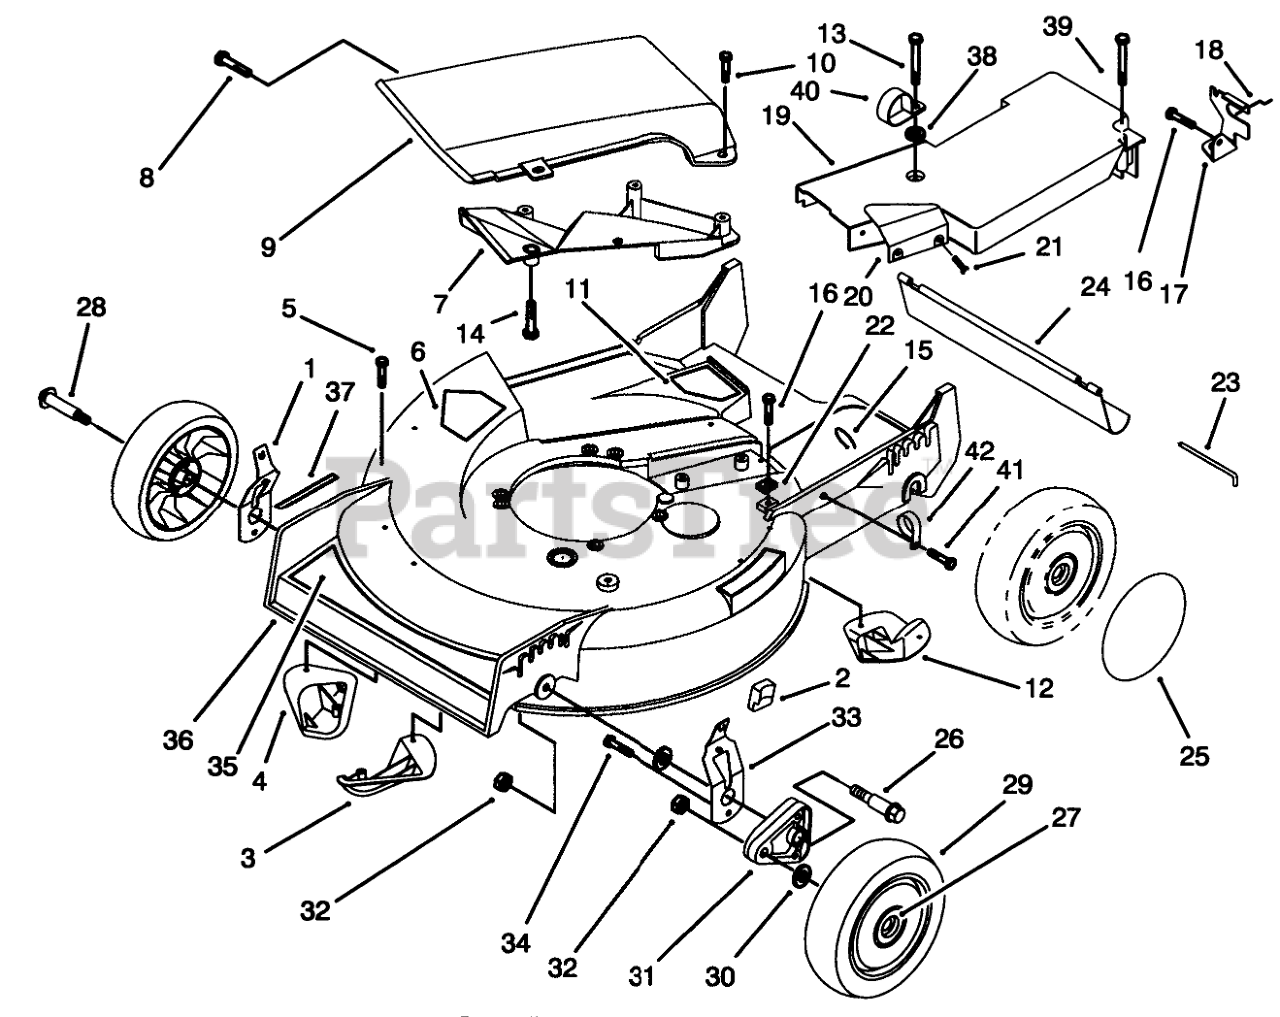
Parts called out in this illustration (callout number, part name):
1	RH SPRING ARM ASM
2	KNOB-ARM
3	KICKER-FRONT
4	KICKER-RH
5	SCREW-PPH
6	DECAL-DANGER
7	Deflector-Recycler
8	SCREW AND WASHER ASM
9	Cover Assembly (Incl. Ref. #7 & 14)
10	SCREW-HWH
11	DECAL - DANGER
12	KICKER-REAR
13	SCREW-SPECIAL
15	TIE-CABLE
16	SCREW-HWHTF
17	Bracket-Adj. Trac
18	RETAINER-CABLE
19	Belt Cover Assembly (Incl. Ref. #20 & 21)
20	HEAT SHIELD
21	RIVET-HEAD, FLAT
22	CLAMP-CABLE
23	ROD-SHIELD
24	SHIELD-TRAILING
25	WHEEL COVER
26	BOLT-SHOULDER
27	BUSHING
28	BOLT-WHEEL
29	Wheel & Tire Assembly ,(Incl. Ref. #27)
30	WASHER
31	ARM-PIVOT, FRONT
32	NUT-LOCK
33	LH SPRING ARM ASM
34	SCREW-HWH
35	DECAL - DECK
36	Housing Assembly (Incl.Ref.#3,4,5,6,11, 12, & 37 Pg.1-2) (Incl. Ref. # 6-7 Pg.3)
37	DECAL - HOC
38	WASHER
39	SCREW-HHFTF
40	CLAMP-CABLE
41	SCREW-HWH
42	CLAMP-CABLE
